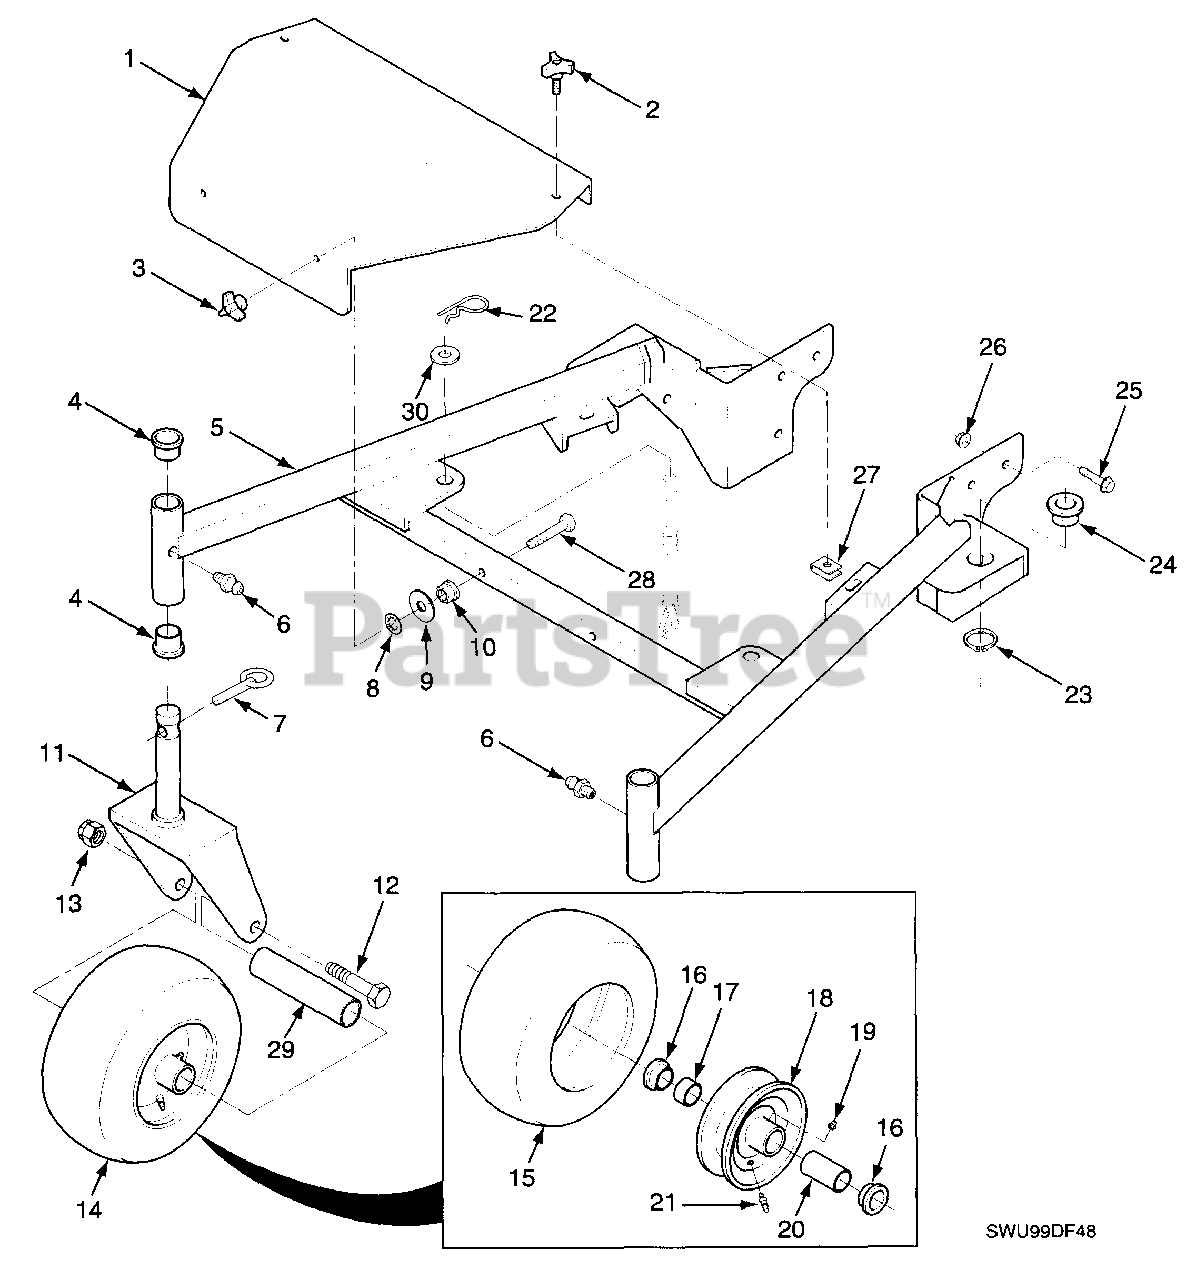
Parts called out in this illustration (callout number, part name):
1	Belt Cover With Decal
2	Knob With Stud
3	Knob, Deck Cover Mounting
4	Bushing, Caster
5	Frame Weldment, Deck Mounting - 48"
6	Grease Fitting Str 1/4-28 Self Tap
7	Quick Pin, 438 Dia
8	Nut, Push-On - 3/8 Thd
9	Flatwasher, 3/8 (.391 x .938 x .105)
10	Nut, 3/8-16 Serrated Flange Hex Head
11	Yoke, Caster Wheel
12	Capscrew, Hex Head 1/2-13 x 6.50"
13	Locknut, 1/2-13 Elastic Stop
14	Wheel Assembly, Caster
15	Tire, 11 x 4.00-5
16	Retainer
17	Roller Bearing
18	Rim, 5.0 x 2.75 With Zerk & Valve
19	Grease Fitting Str 1/4-28
20	Roller Bearing .625 x 3.25"
21	Tire Valve
22	Hair Pin Cotter, .177 x 3.25"
23	Retaining Ring 1.50 Ext
24	Bushing, Deck Adjustment Pin
25	Capscrew, Hex Head 7/16-14 x 1.0"
26	Nut, 7/16-14 Serrated Flange Hex
27	U-Nut, 3/8-16
28	Capscrew, Hex Head 3/8-16 x 2.25"
29	Sleeve, Caster Wheel
30	Flatwasher, 5/8 - (.688 x 1.75 x .134)
